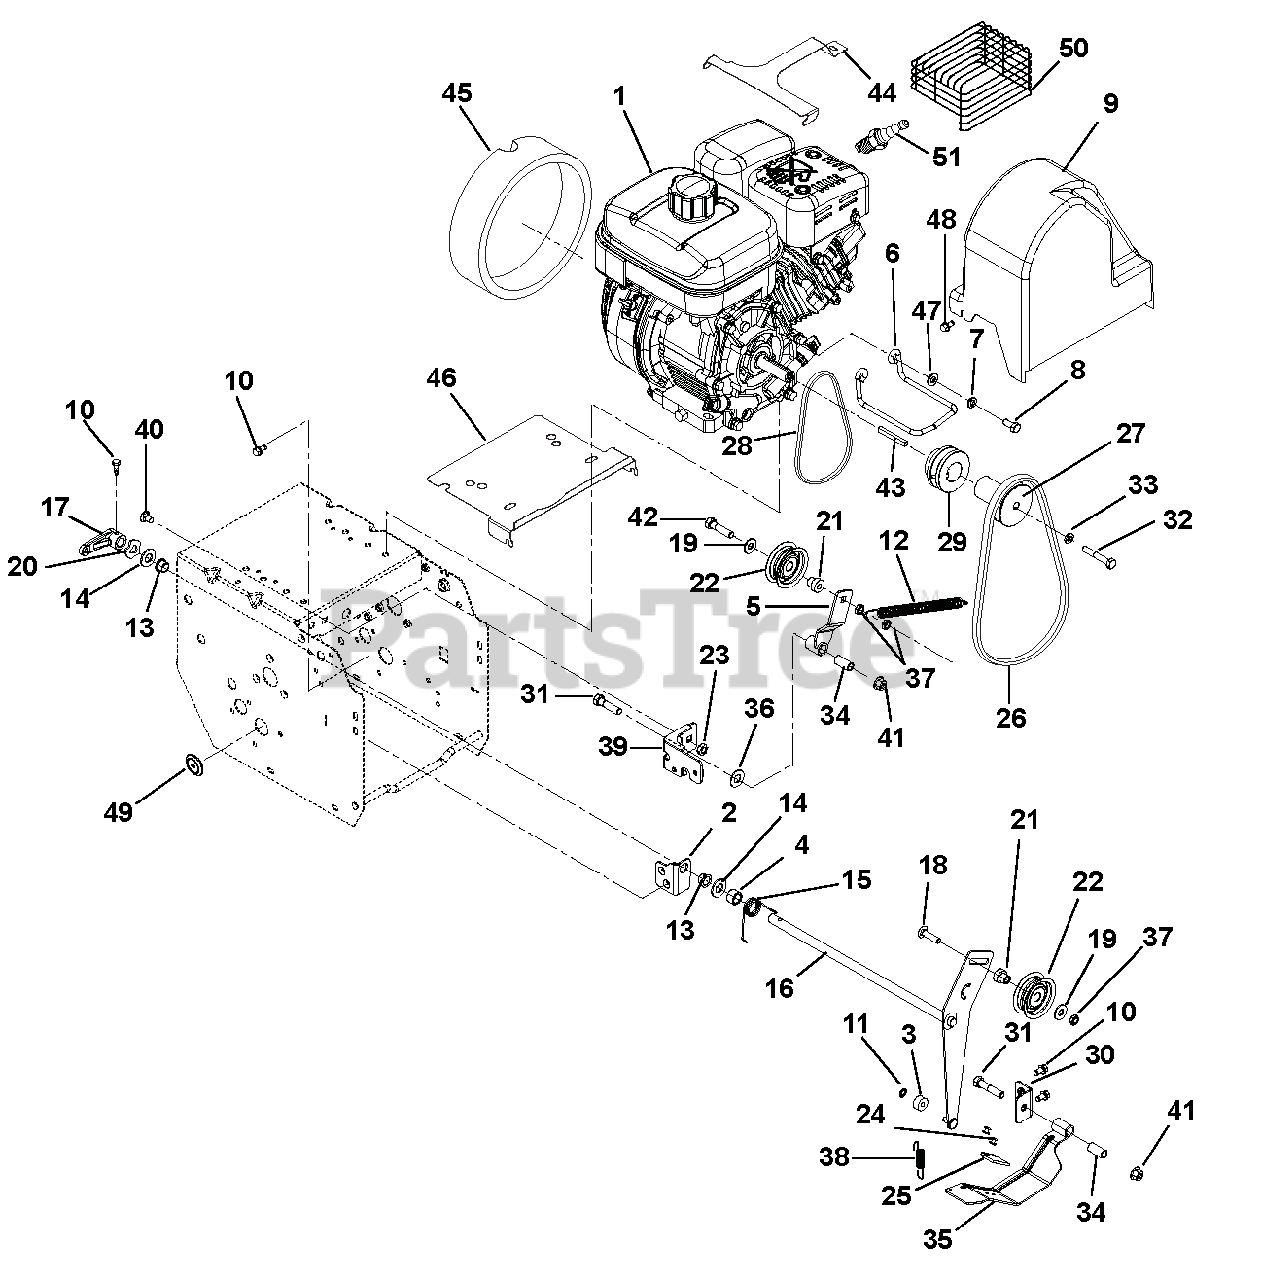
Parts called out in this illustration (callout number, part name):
1	SUBARU EX17 120V ALL-SEASON
2	BRACKET, MOUNT - IDLER ARM
3	BSHG,SLV .270 X .750 X .250
4	BSHG-SLV .510X.751X.475
5	WELDMENT, TRACTION IDLER ARM
6	BELT FINGER
7	WSHR-LK .312X.097 HVY YWZC
8	BLT-HEX .31-24X.75 YWZC GR5
9	BELT COVER
10	SCR-TAP .25-20X.50 HWH TR YWZ
11	RG-RTNG-EXT .250X.010
12	SPRING, EXTENSION
13	BUSHING, POLYLINER-.50 SPLIT
14	WSHR-FL-STL.531X1.00X.063 YWZC
15	SG-TORS .075 X .955
16	WELDMENT, ATTACHMENT IDLER ARM
17	ARM, CLUTCH - ATTACHMENT
18	BLT-RDHDSQSHNK.31-18X1.13 G5YZ
19	@WSHR-FL-STL.38X.875X.083 YWZC
20	WSHR-WAVE .50X.75X.015 .13FRHT
21	SPCR, BRG .315X.50X.688X.281
22	IDLER
23	@NUT-LK-TOP-FLG .31-18 YWZC
24	RVT-POP .187 YZ
25	PAD, BRAKE
26	V-BELT, HA-RAW EDGE
27	SHEAVE, ATTACHMENT DRIVE
28	V-BELT, 3L-WRAPPED
29	PULLEY, TRACTION
30	BRACKET, MOUNT - BRAKE
31	@BLT-HEX .38-16X1.75 GR5 YWZC
32	@BLT-HEX .31-24X1.75 GR5 YWZC
33	WSHR-LK .312X.097 HVY YWZC
34	BSHG-SLV .385X.500X1.045
35	BRAKE ARM W/PAD
36	@WSHR-FL-STL.406X.812X.065 YWZ
37	@NUT-LK-CTR-JAM .31-18 YWZC
38	SPRING-EXT .437 X .438 X 2.64
39	WELDMENT, FRAME BRACKET
40	@BLT-RHDSSQNK .31-18X.62 G5YZ
41	@NUT-LK-TOP-FLG .38-16 YWZC
42	@BLT-HEX .31-18X1.50 GR5 YWZC
43	KEY-SQ .188X.75X.188
44	GUARD, SNOW-SUBARU EX17
45	FOAM COVER, RECOIL-SUBARU
46	BAFFLE,ENGINE,SMALL BLOCK
47	@WSHR-FL-STL.344X.688X.065YWZC
48	SCR-TAP .25-20X.50 LGHWH TR YZ
49	PLUG, HOLE - .875" NYLON
50	GUARD,MUFFLER,SUB 20A-37303-11
51	PLUG, SPARK - TEC. SNO-THRO
